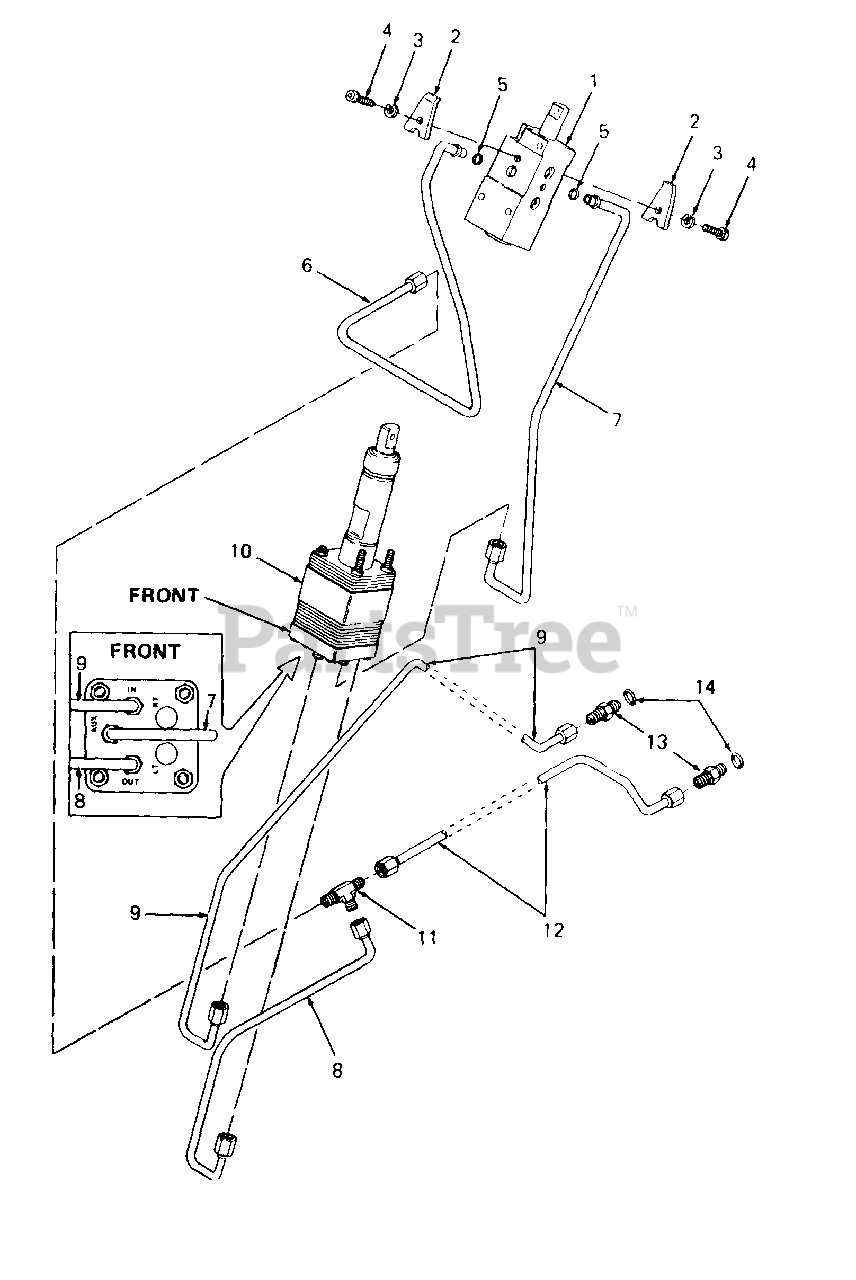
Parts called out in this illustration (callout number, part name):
1	Valve, Lift
2	Clamp, Single
3	Washer, Lock, 1/4
4	Screw, Socket Hd Cap, 1/4-20 x .62 Lg GR8
5	O-Ring, .301 x .070 Dia
6	Tube Assy, P.S. Return - Upper
7	Tube Assy, P.S. Aux
8	Tube Assy, P.S. Return
9	Tube Assy, P.S. Inlet
10	Power Steering Box w/Flat
11	T-Fitting
12	Tube Assy, P.S. Return - Lower
13	Connector, 37 Deg Tube
14	O-Ring, 3/8 OD Tube
